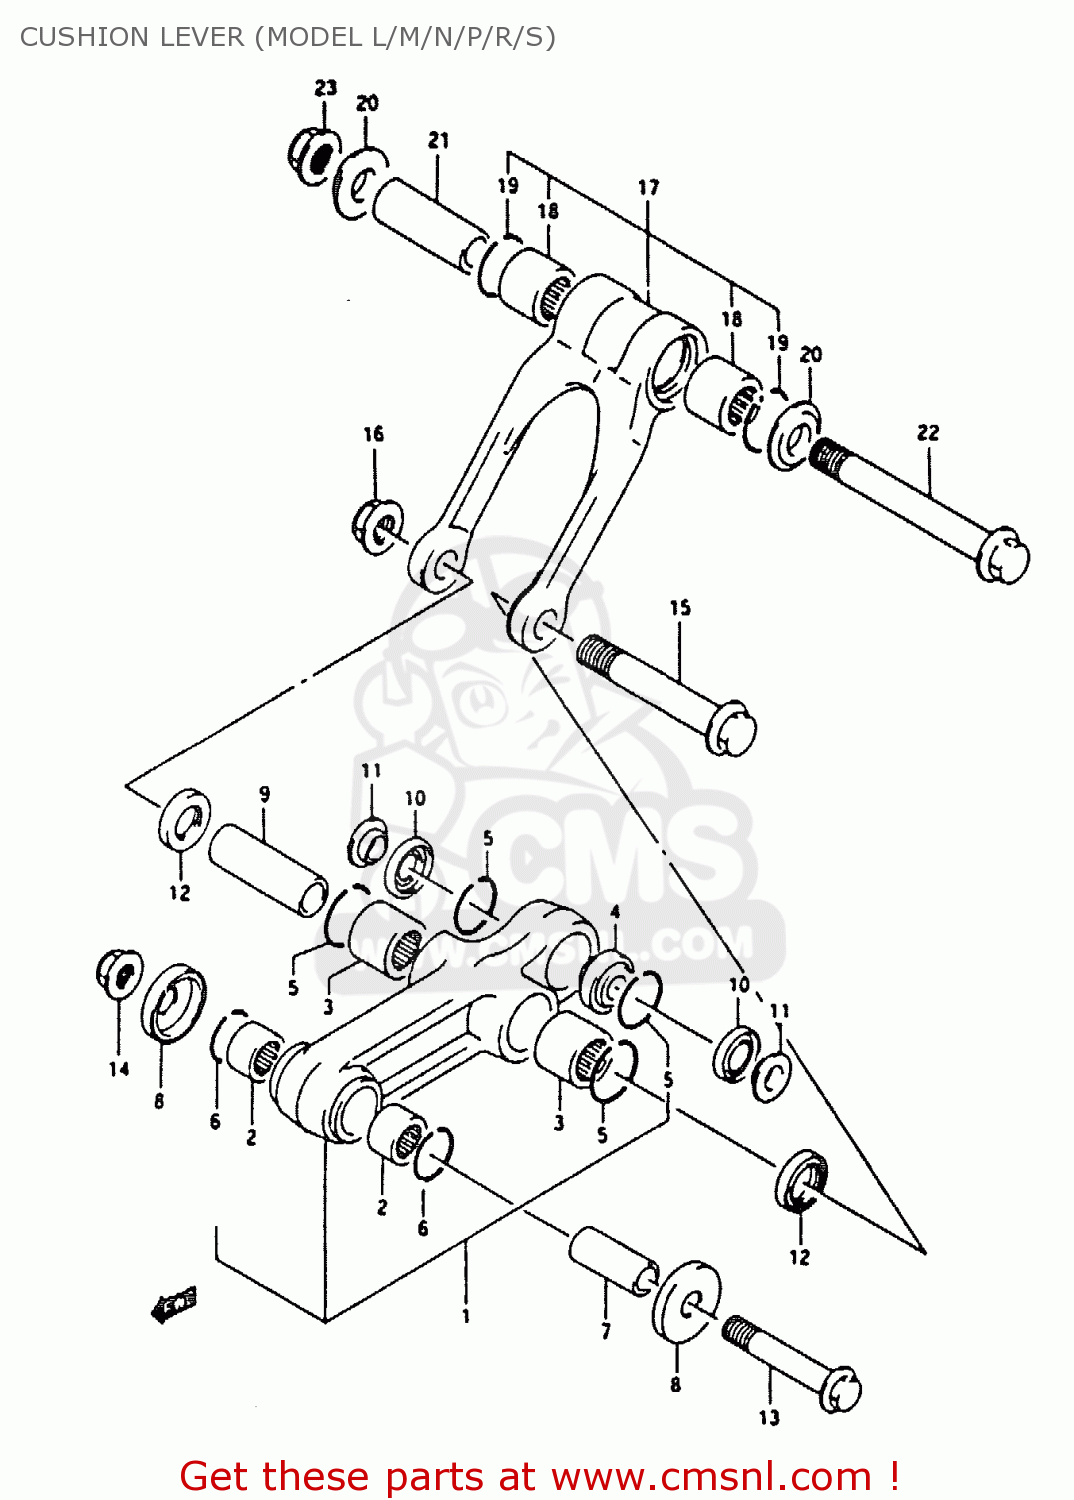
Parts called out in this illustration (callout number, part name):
1	LEVER SET,RR CUSHION
2	BEARING(14X20X12)
3	BEARING(17X24X20)
4	BEARING,RR CUSHION LEVER
5	RING,STOPPER
6	CIRCLIP,PISTON PIN
7	SPACER,RR CUSHION LEVER FR
8	SEAL,REAR CUSHION LEVER
9	SPACER,RR CUSHION LEVER CTR
10	SEAL,RR CUSHION LEVER RR DUST
11	SPACER,RR CUSHION LEVER RR
12	SEAL,OIL(17X24X3)
13	BOLT,RR CUSHION LEVER FR
14	NUT
15	BOLT,RR CUSHION LEVER CTR
16	NUT 12MM
17	ROD SET,REAR CUSHION,LEFT
18	BEARING(17X24X20)
19	RING,STOPPER
20	SPACER,RR CUSHION ROD SIDE
21	SPACER,RR CUSHION ROD
22	BOLT,RR CUSHION ROD
23	NUT 12MM
